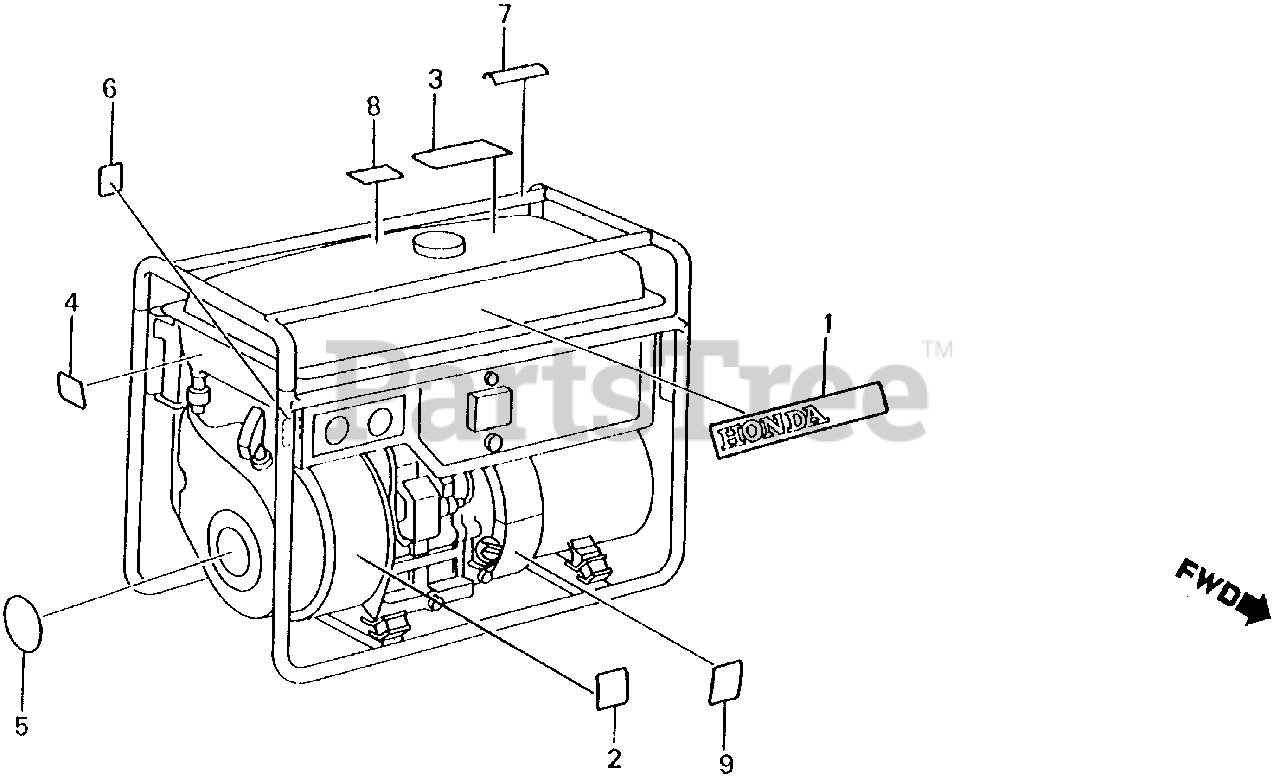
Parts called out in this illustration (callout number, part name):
1	EMBLEM (NOT AVAILABLE)
2	PLATE, CAUTION
3	MARK, CAUTION (ENGLISH/FRENCH)(SPANISH)
4	MARK, CHOKE
5	LABEL, OIL ALERT
6	MARK, AIR CLEANER (ENGLISH)
7	MARK, EX. CAUTION (ENGLISH/FRENCH)
8	MARK, CAUTION (CO)(ENGLISH/FRENCH)(SPANISH)
9	MARK, OIL CAUTION
